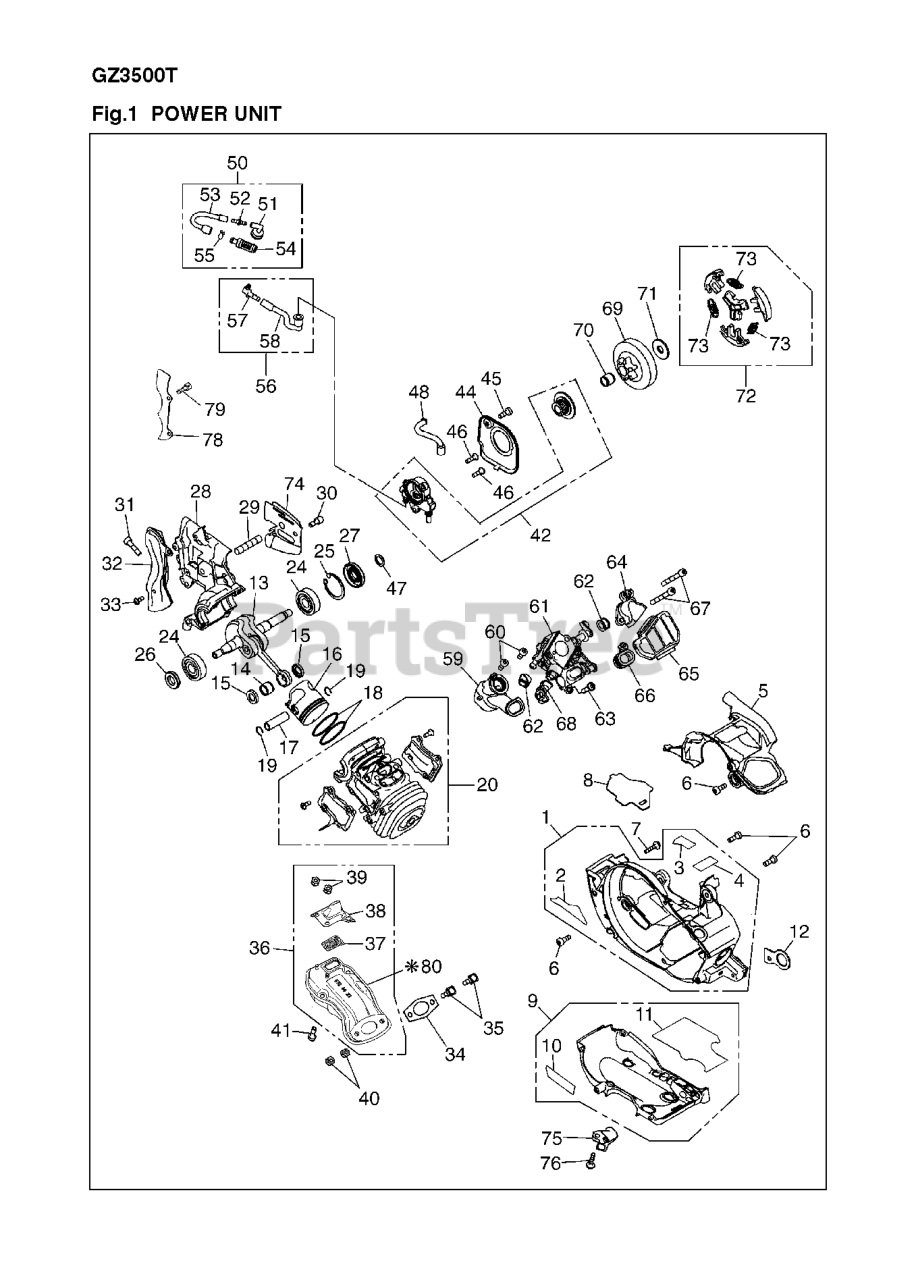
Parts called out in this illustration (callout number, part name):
1	CASE-COMP
3	TAPE, CASE
4	TAPE, CASE
5	COVER TOP
7	SCREW (RPLS 267132210)
9	GUARD, UNDER
9	CASE, ASSY
13	SHAFT COMP
14	BEARING,ROLLER
15	WASHER
18	RING, PISTON
20	CYLINDER ASSY
28	CASE CRANK
29	STUD BOLT
31	SCREW
32	PIPE EXHAUST
33	SCREW
34	GASKET, MUFFLER
36	MUFFLER
37	SPARK ARRESTER
38	GUIDE MUFFLER
38	GUIDE, MUFFLER
39	NUT
42	OIL PUMP SET(RPLS 284155112
44	COVER, PUMP
46	SCREW
47	THRUST WASHER
48	PIPE
51	OIL FILTER
53	PIPE (GZ3500T)
54	RP_FILTER
55	CLIP
56	PIPE IN COMP
57	ELBOW
58	PIPE, OIL IN
61	CARBURETOR ASSY
64	MANIFOLD
66	SEAL RPLS 848CE083G2
67	BOLT
68	GUIDE, CAB
70	ROLLER BEARING
71	PLATE
72	CLUTCH-ASSY
75	CATCHER (RPLS -66F1)
76	SCREW (RPLS 267132210)
80	MUFFLER
